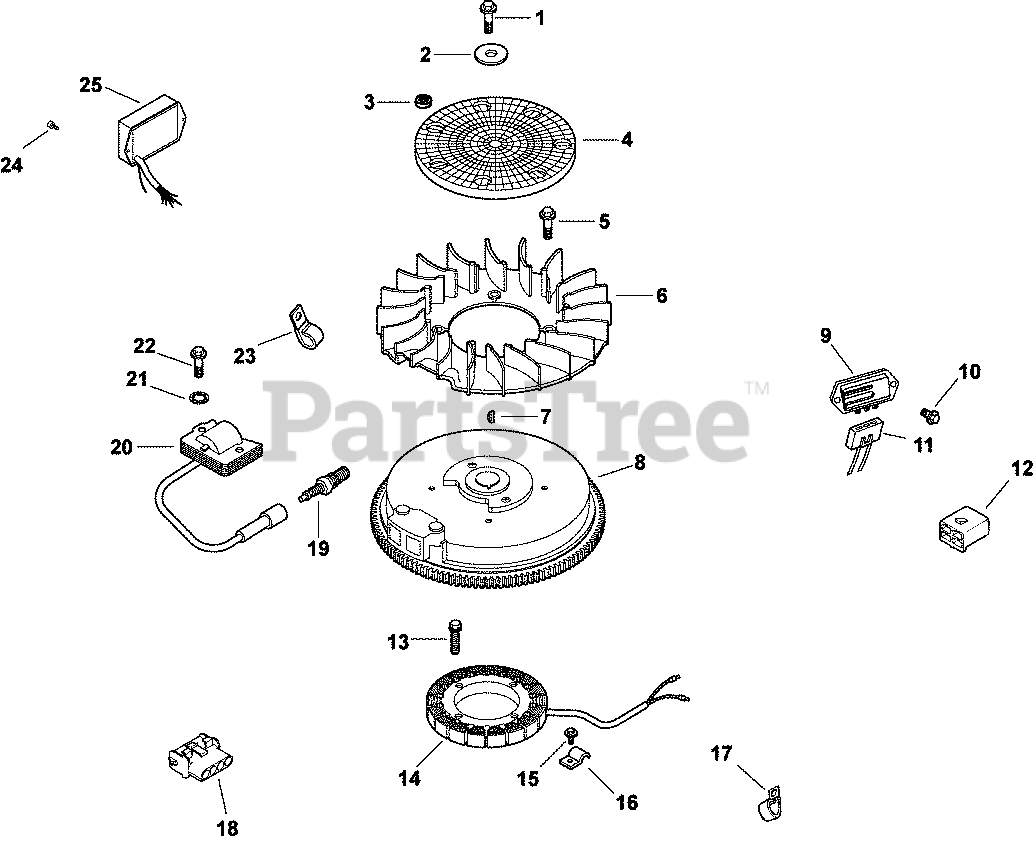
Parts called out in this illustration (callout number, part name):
1	SCREW, FLG M10X1.5X45 - (#25086361S)
2	WASHER, FLAT 13/32"
4	SCREEN, GRASS
5	BOLT, SHOULDER
7	KEY, 3/16" X 5/8"
8	FLYWHEEL - DISCONTINUED
9	REG/RECT-15 AMP (KM)-USE 41 403 10-S
10	SCREW, WSH HD TAP #8-18X1"-DISC.
11	CONNECTOR, BODY (KM)-USE 25 155 41-S
12	CONNECTOR
13	SCREW, M5X0.8X25 - (#25086402S)
14	STATOR - USE 12 085 09-S
15	SCREW, FLG THD FRM M5X.8X10
17	CLIP, REGULATOR/RECTIFIER
18	CONNECTOR
19	PLUG, SPARK (STD)
20	MODULE, IGNITION
21	WASHER, INT TOOTH LOCK 1/4"
22	SCREW, SCKT THRD FRMM5X0.8X20 - DISCONTINUED
23	CLIP, CABLE
24	SCREW, PHL THD FRM M4.2X13
25	MODULE, DIGITAL SPD ADV-USE 12 707 01-S
